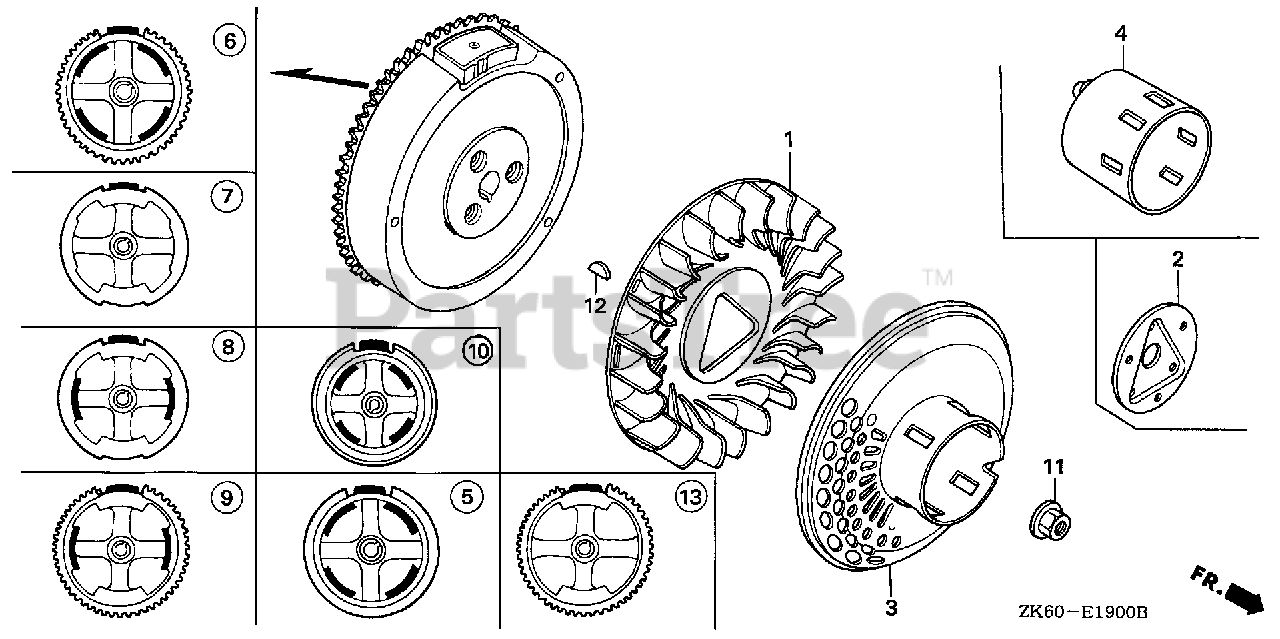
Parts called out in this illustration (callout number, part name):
1	FAN, COOLING
4	PULLEY, STARTER
11	NUT, SPECIAL (16MM)
12	KEY, SPECIAL WOODRUFF (25X18)
